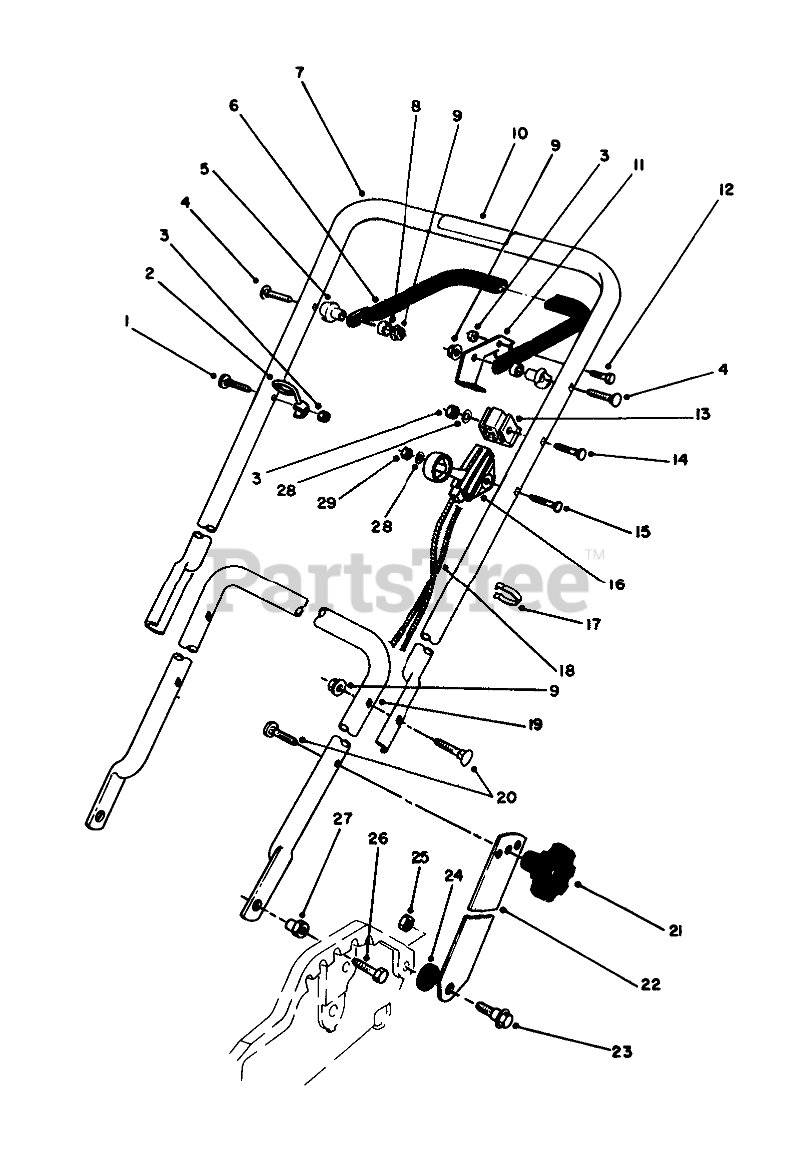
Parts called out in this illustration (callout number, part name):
1	HANDLE SCREW
2	Guide
4	5/16-18 X 2 HNDLE SCREW
5	SPACER-SUPPORT
6	Bar-Control
7	Handle-Upper (Incl. Ref #10)
8	SPACER-NYLON
9	NUT-LOCK, NI
10	DECAL - HANDLE
11	Lever-Control
12	SCREW-HH
13	SUPPORT-CABLE
14	HANDLE SCREW
15	SCREW-HANDLE
16	THROTTLE CONTROL
17	BOWDEN CLIP
18	BRAKE CABLE
19	LOWER HANDLE
20	SCREW
22	Handle Latch
23	SCREW-SHOULDER
24	SPACER
25	NUT-LOCK, NI
26	SCREW-HH
27	HANDLE PIVOT NUT
28	WASHER-FLAT
29	NUT-LOCK, NI
